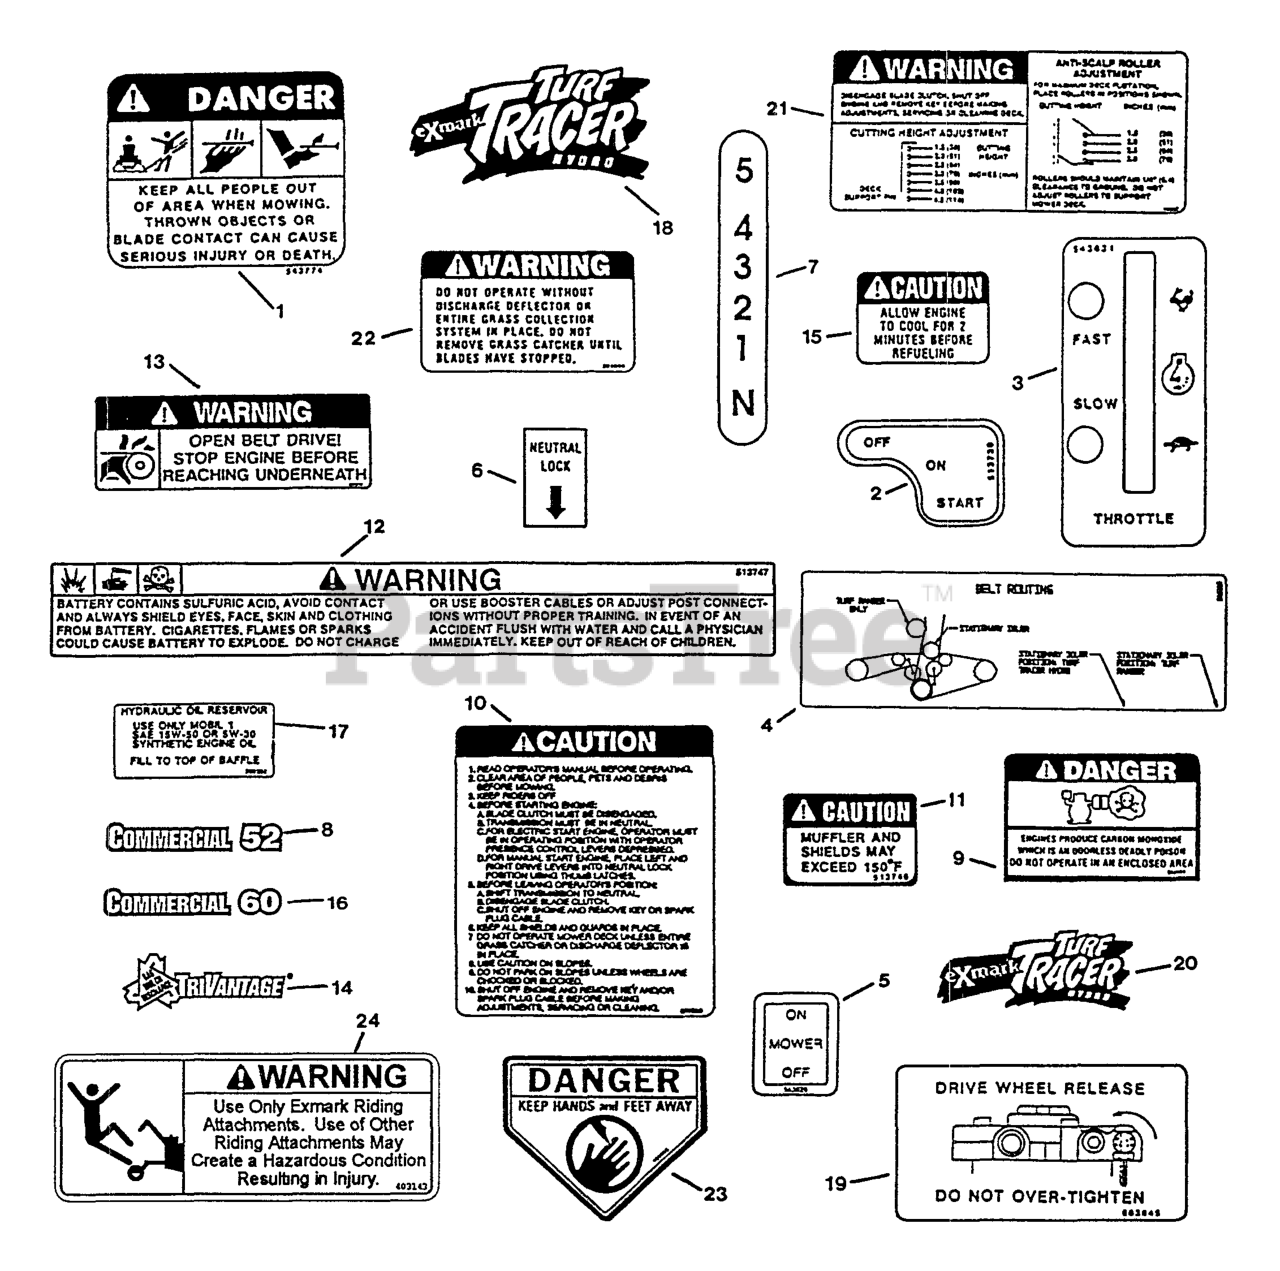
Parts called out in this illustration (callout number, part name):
1	DECAL-DANGER
4	DECAL,BELT ROUTING
5	DECAL-MOWER SWITCH
6	DECAL,NEUTRAL LOCK
7	DECAL - SHIFTER
8	DECAL,COMMERCIAL 52
12	DECAL-BATTERY
13	DECAL,BELT DRIVE
16	DECAL,COMMERCIAL 60
17	DECAL,HYD TANK
19	DECAL,DRIVE RELEASE
22	DECAL-WARNING, DISCHARGE
23	DECAL-DANGER
24	DECAL,SULKY WARNING
